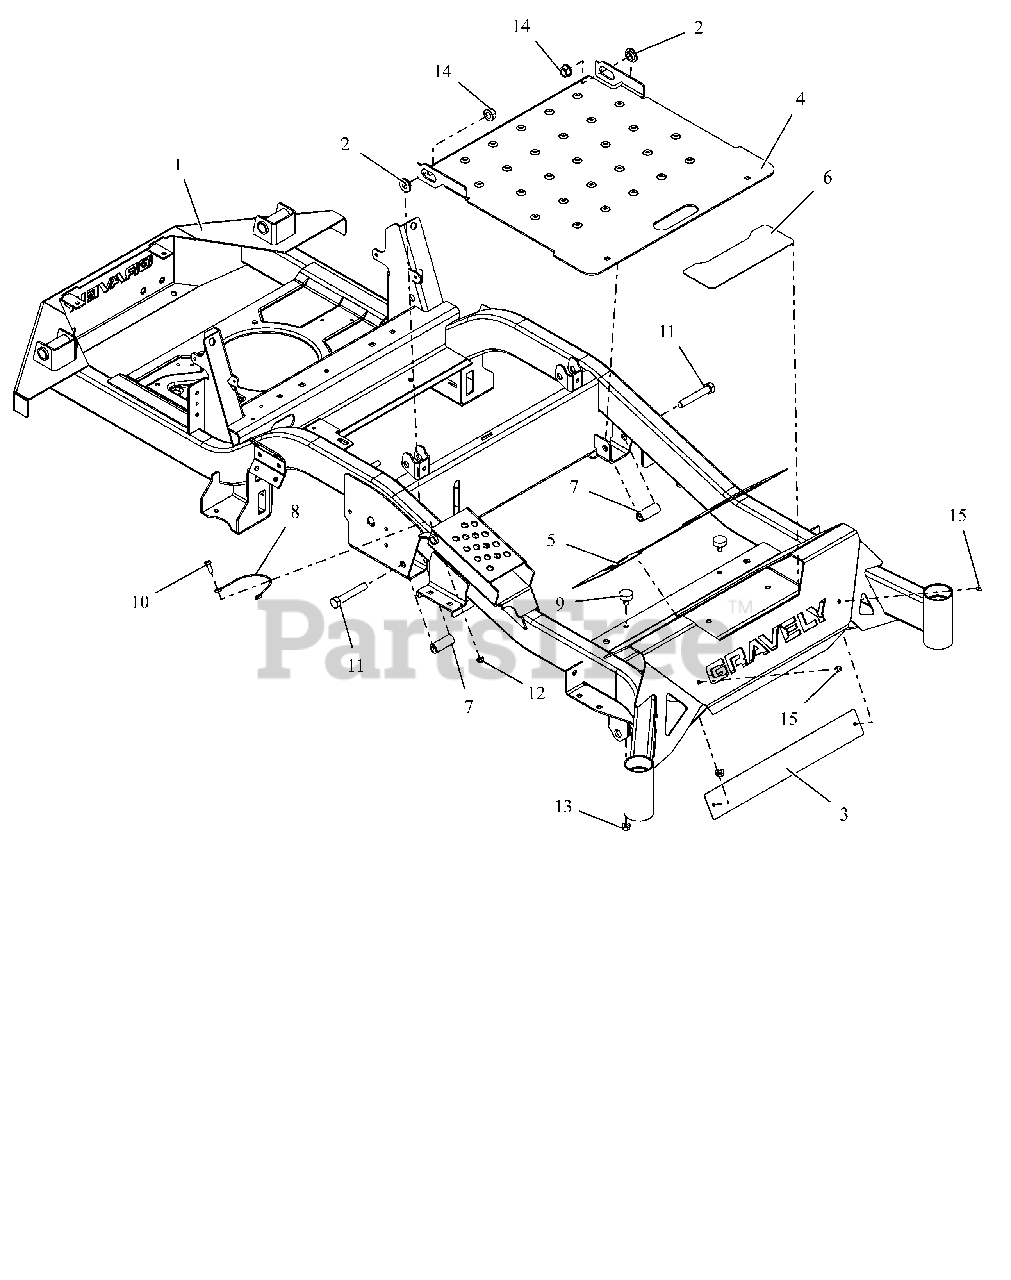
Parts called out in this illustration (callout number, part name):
1	HD 44-52 FRAME W/SAFETY DECALS
2	BSHG-FLG .515X.750X.310X1.120
3	PLATE, BACK FOOT-REST XL
4	KIT,ACCESS PANEL W/DECALS-RED
5	GRIP, FRONT
6	GRIP, STEP
7	SPACER, .515X.75X1.83
8	CABLE, 12.0 LANYARD, NYLON
9	BUMPER, RUBBER
10	BLT, HEX .25-20X.75 G5 ZCC
11	BLT, HEX .50-13X3.00 G5 ZCC
12	NUT,NYL-FLG .25-20 GF ZCC
13	NUT,SPNLK-FLG .31-18 G5 ZCC
14	NUT-LK-TOP-FLG .500-13 GF ZCC
15	RIVET, .1875 AL/AL .126-.250
